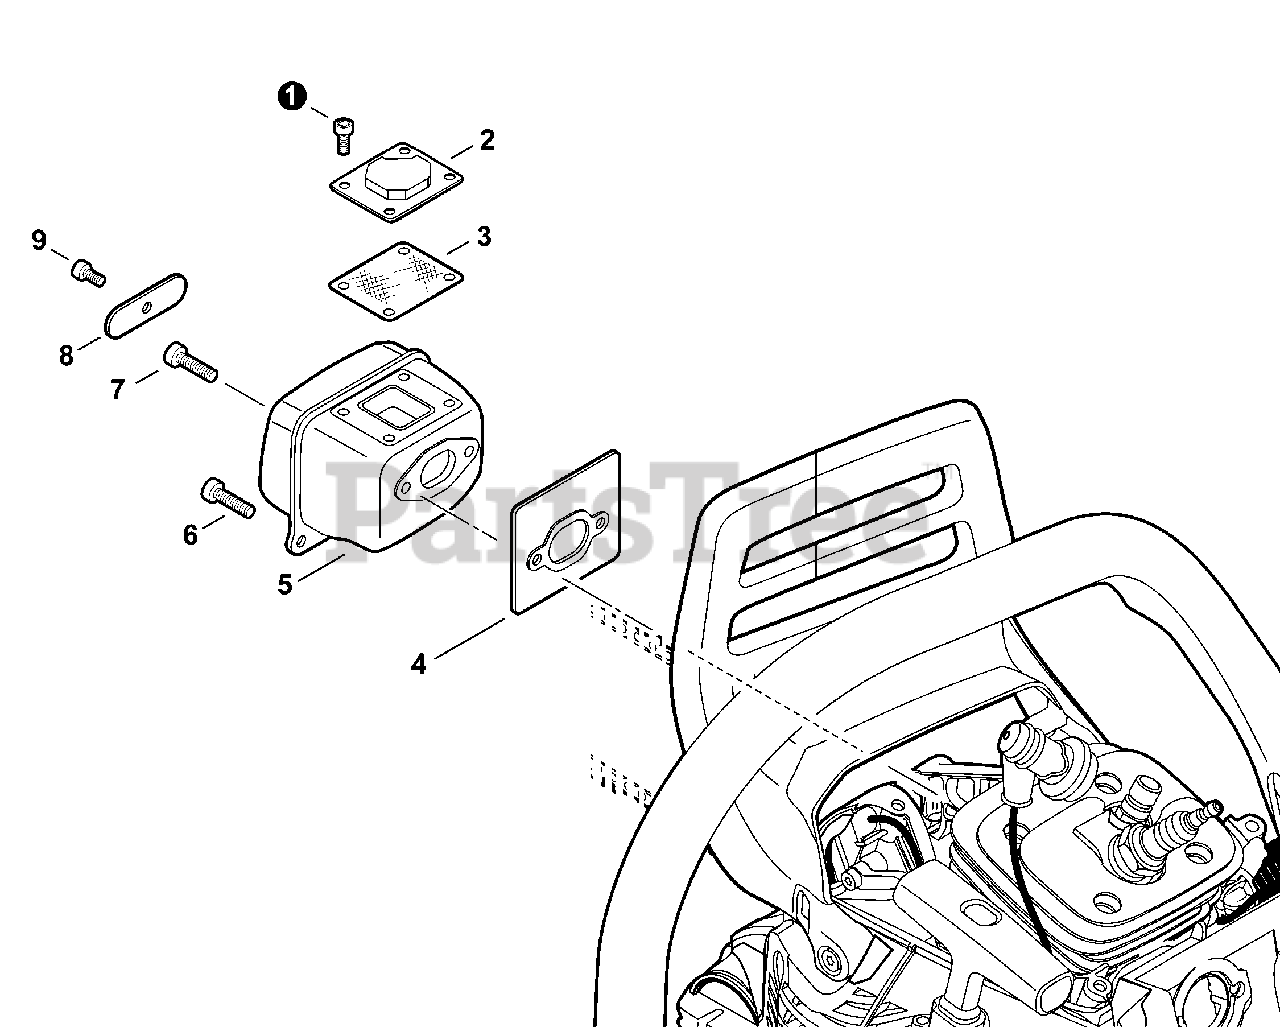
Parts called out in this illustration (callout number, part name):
1	BOLT, TORX 4×8
2	GUIDE, EXHAUST
3	SCREEN, SPARK ARRESTER
4	GASKET, EXHAUST
5	MUFFLER
6	BOLT, TORX 5×20
7	BOLT, TORX 5×20
8	PLATE, MUFFLER
9	BOLT, TORX 4×8
